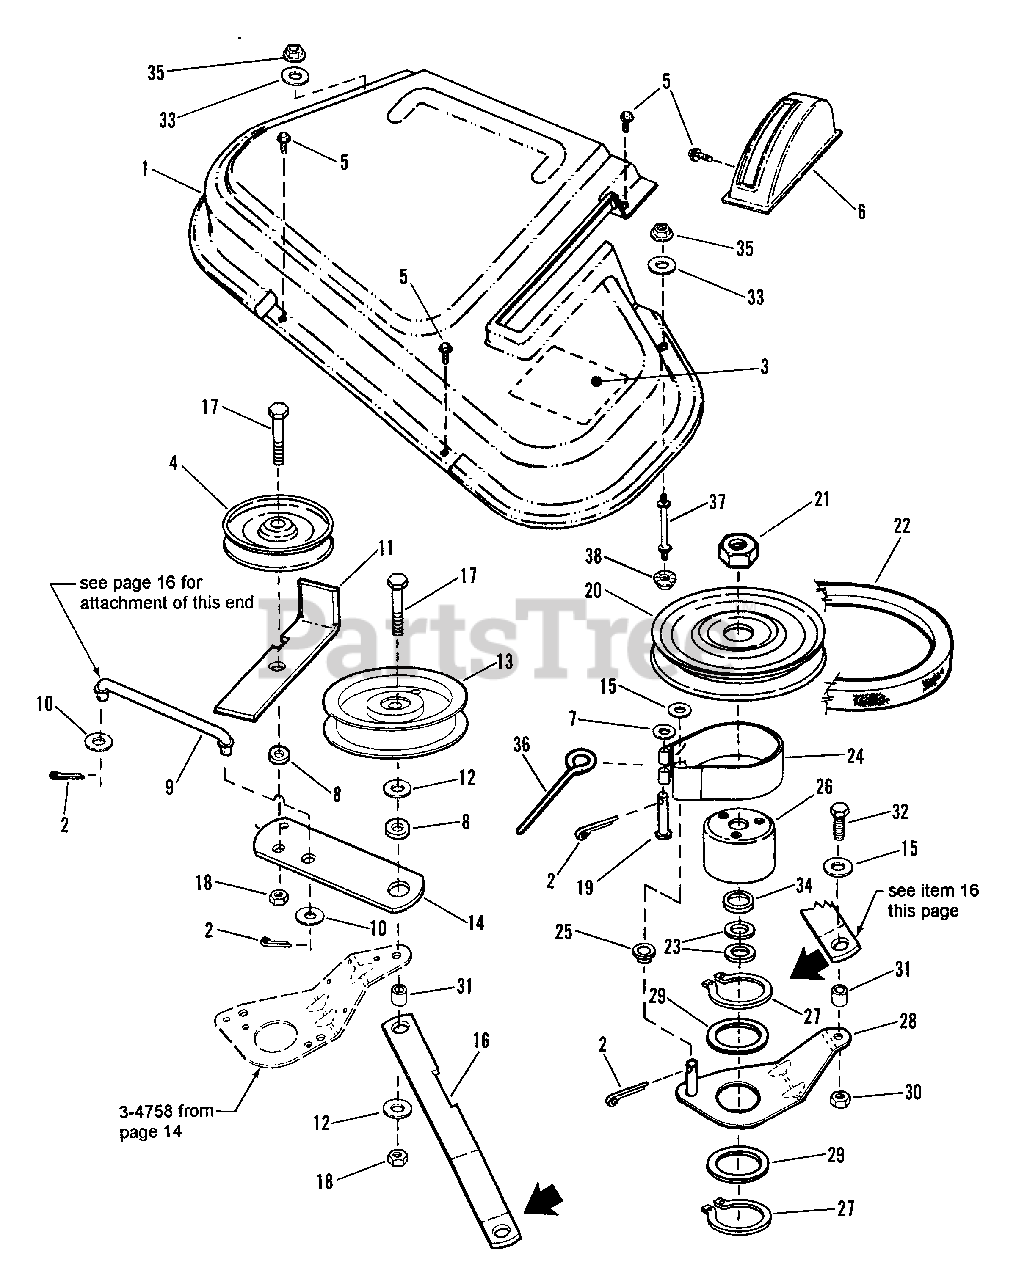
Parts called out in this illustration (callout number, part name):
1	COVER, Spindle 42"
2	PIN, 3/32 x 3/4 Cotter
3	DECAL, Brake Operation
4	PULLEY, Seam Welded Idler
5	SCREW, 1/4-20 x 5/8" Self-Tapping
6	COVER, Lift Quadrant
7	WASHER, 1/4 Flat
8	SPACER, 21/64 x 5/8 x 5/32
9	LINK, Idler
10	WASHER, 3/8" Flat
11	GUIDE, Belt
12	WASHER, 11/32 Flat
13	PULLEY, 4 1/8" Flat Idler
14	ARM, Idler Dual
15	WASHER, 3/8" Flat
17	SCREW, 5/16-24 x 1-3/4" Hex Head Cap
18	NUT, 5/16-24 Yellow Zinc Hex Center Lock
19	PIN, 1/4 x 1-5/8" Clevis
20	PULLEY, 5" O.D.
21	NUT, 3/4-16 Hex Jam
22	BELT, "5L" Section 42"
23	WASHER, 3/4 Flat
24	ASSEMBLY, Brake Band
25	SPACER
26	DRUM, Brake
27	RING, 2" External Retaining
28	ASSEMBLY, Brake Arm
29	WASHER, 2" I.D. Nylon
30	NUT, 3/8-24 Hex Center Lock
31	SPACER
32	SCREW, 3/8-24 x 3/4" Hex Head Cap
33	WASHER, 11/32 x 11/16 x 1/16 Flat
34	SPACER, 3/4 I.D.
35	NUT, 5/16-18 Flange Lock
36	BOLT, 5/16-18 x 3" Eye
37	STANDOFF, 3-1/2"
38	NUT, 3/8-16, Hex Flange Lock
